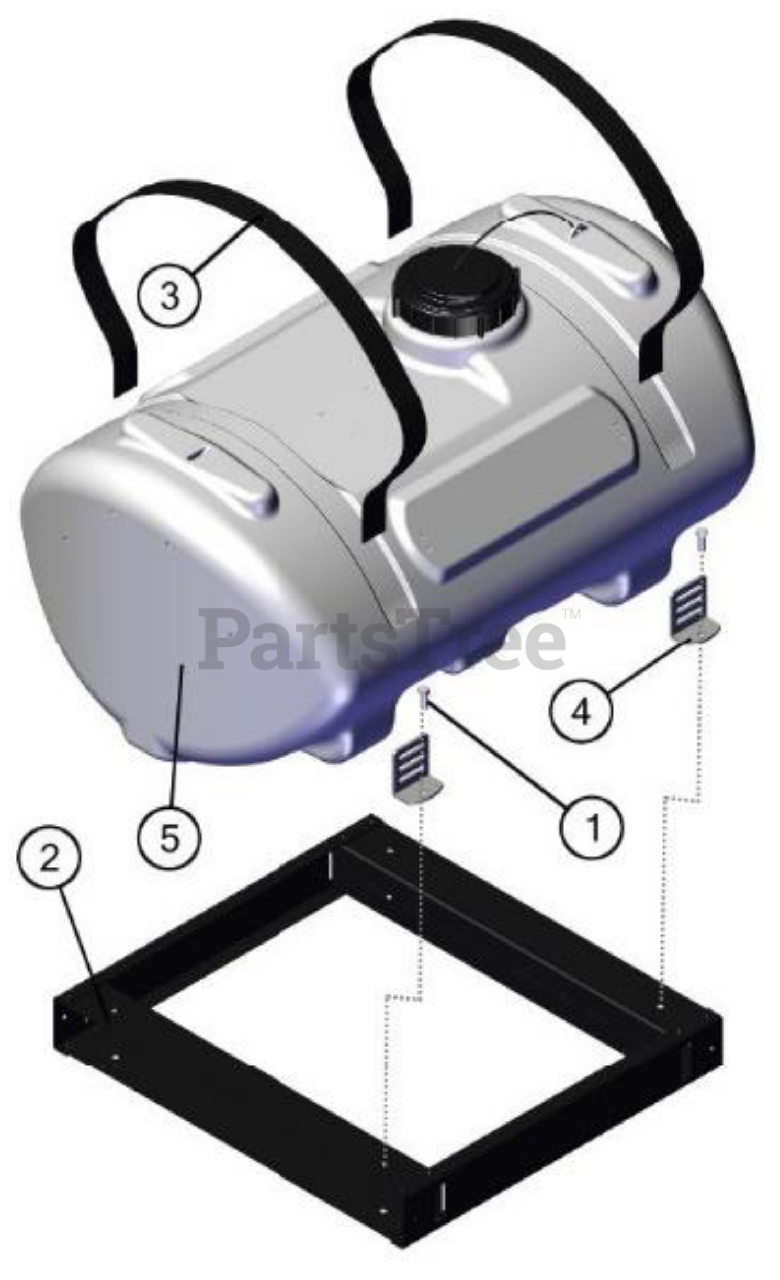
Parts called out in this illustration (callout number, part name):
1	BOLT 3/8-16X1"
2	NYLON NUT 3/8"
3	40 GALLON STRAP
4	TIE DOWN CLAMP STRAP 1.5"
5	40 GALLON TANK
